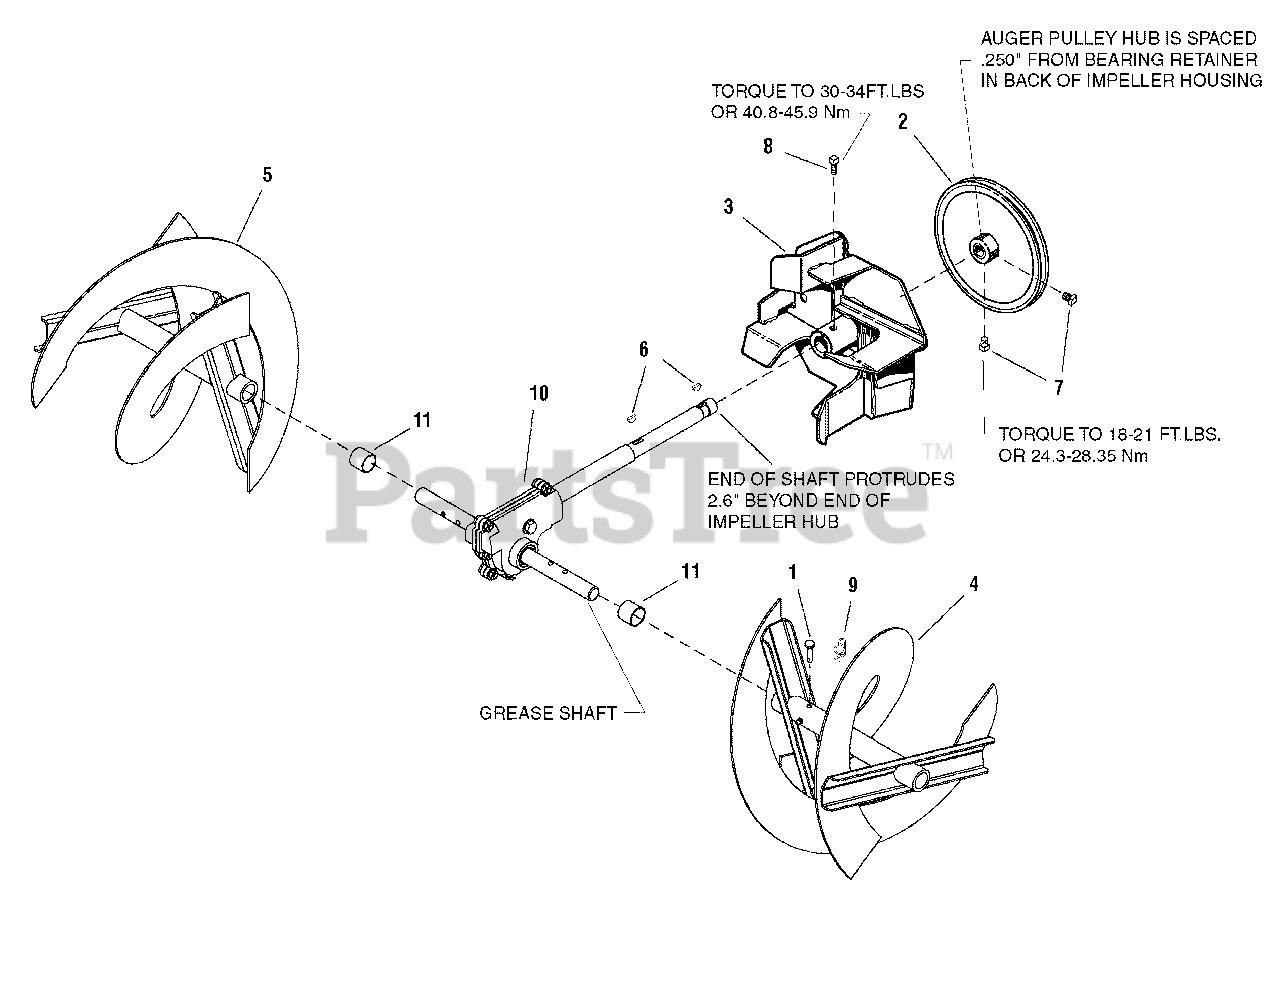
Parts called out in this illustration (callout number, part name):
1	PIN, Shear
2	PULLEY, Auger Input
3	IMPELLER ASSEMBLY
4	AUGER ASSEMBLY, L.H., 22" Housing
5	AUGER ASSEMBLY, R.H., 22" Housing
6	KEY, Woodruff
7	SCREW, Set Square Head Cup Point 5/16-18 x 1/2 G8
8	SCREW, Set Square head Cup Point 3/8-16 x 1/2 G8
9	COTTER PIN, 1/4" Self Locking
10	GEAR BOX ASSEMBLY, Auger Drive
